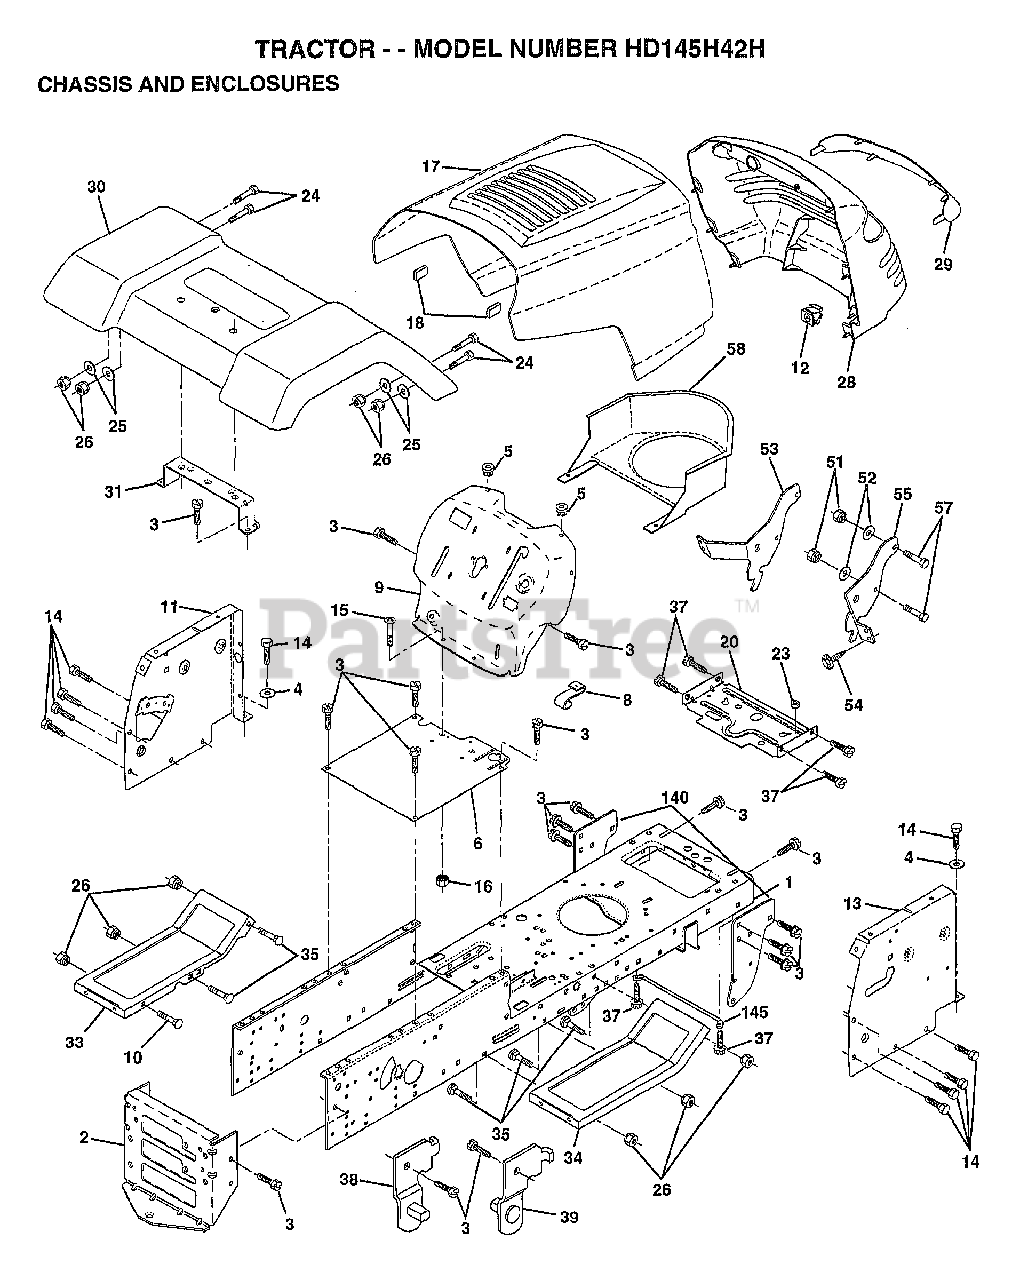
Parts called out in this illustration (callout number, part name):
3	SCREW
4	WASHER
5	BUMPER-HOOD/DASH
6	SADDLE
8	CLIP.RETAINER
9	DASH SILKSCREEN
11	"PANEL-DASH,LH"
12	CLIP.TINNERMAN
14	SCREW LT
15	SCREW
17	"HOOD W/TRIM,MS428"
20	"PLATE-MTG,BATT/FU"
24	BOLT
25	WASHER
26	NUT
28	GRILLE-MS428
29	LENS GRILLE
30	FENDER ASM
31	BRKT FENDER
33	FOOTREST LH
34	FOOTREST RH
34	BOLT
37	SCREW LT
38	BRACKET ASM LH
39	BRACKET ASM RH
51	NUT
52	WASHER
53	BRACKET.GRILLE.LH
54	SCREW.HEX.WS.HD
55	BRACKET.GRILLE.RH
58	AIR DUCT
140	BRKT SUSPENSION
145	"ROD POVOT,CHASSIS"
